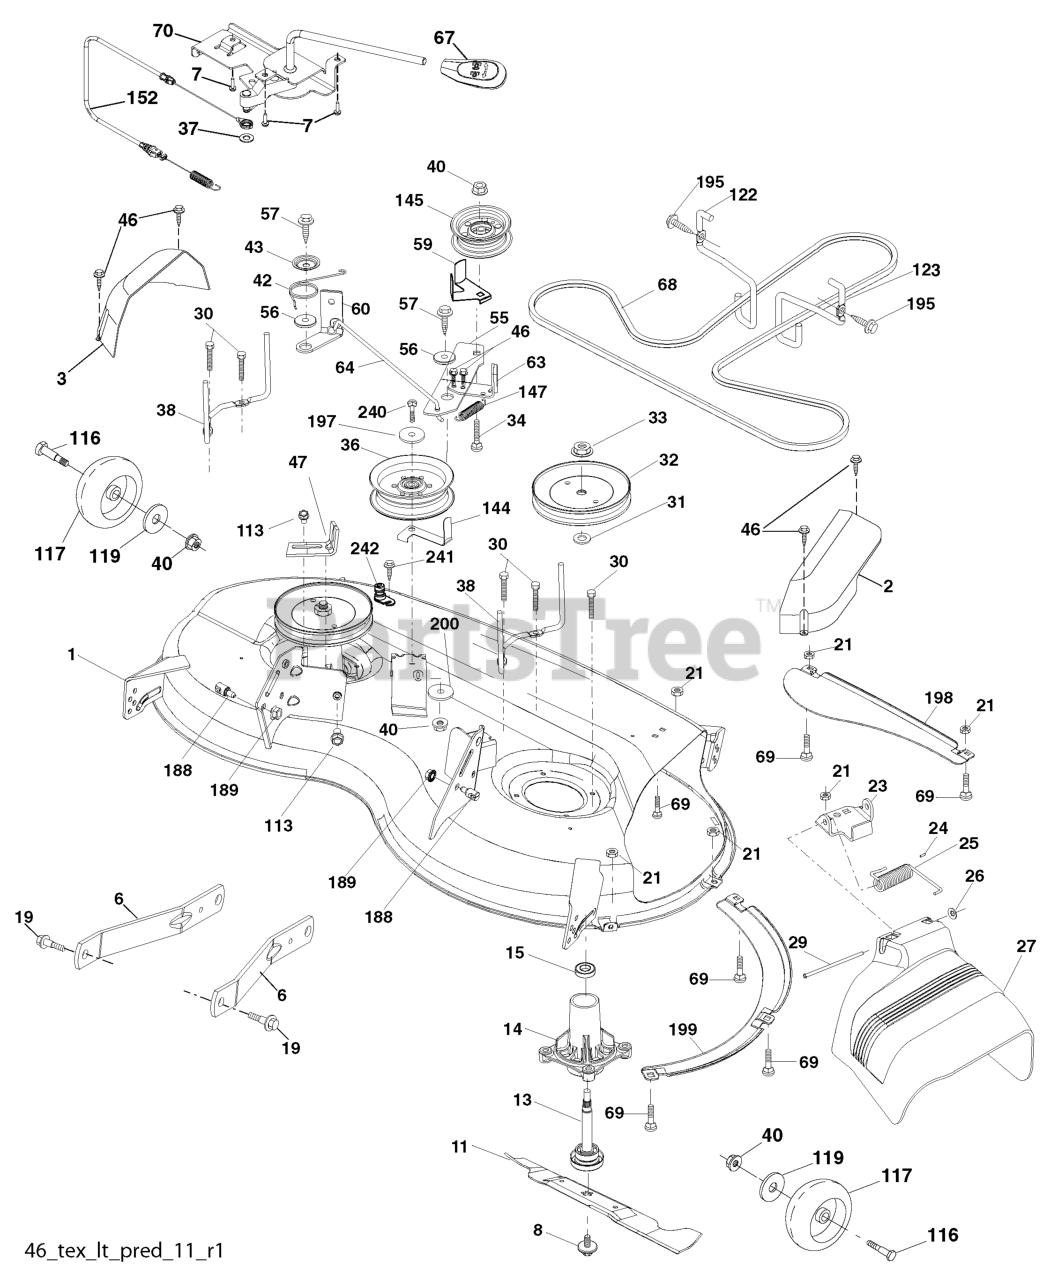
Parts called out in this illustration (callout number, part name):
1	DECK.WELDMENT.46"
2	COVER.MANDREL.RH.46"
3	COVER.MANDREL.LH.46"
6	ARM.SUSPENSION.MOWER.R
7	SCREW.#10 X 0.750.BOS
8	BOLT.WASHER.ASM.7/16-2
11	BLADE.MOWER.46".HI.LIFT
13	SHAFT.ASM.MDRL.N/GREASE.38
14	RP.HOUSING.MANDREL.4PT.
19	BOLT.SHOULDER
21	LOCKNUT
23	BRKT.DEFLECTOR.38"2005+
24	CAP-SLEEVE LT
25	SPRING.TORSION.DEFLECT
26	NUT PUSH M
27	SHIELD.DEFLECTOR.MOWER.46"BLAC
29	ROD.HINGE
30	SCREW, WASHER HEAD
31	WASHER.SPACER.MANDREL
32	PULLEY.MANDREL.5.438.PD
33	NUT.FLANGE.LOCK.TOP
34	BOLT.3/8-16X1.50
36	PULLEY.IDLER.2006
37	WASHER
38	KEEPER.BELT.MANDREL.PULLEY
40	NUT LOCK FLG 3/8-16 UNC
42	SPRING.TORSION.BRAKE
43	SRPING.TORSION.RETAINE
46	SCREW.1/4-20X5/8
47	BRKT.CLUTCH.CABLE
55	IDLER.ARM
56	SPACER.RETAINER
57	SCREW 3/8-16X1
59	GUARD, BELT
60	ARM BRAKE MOWER RH 38"
63	ARM BRAKE MOWER
64	LINKAGE BRAKE
67	HANDLE.CLUTCH.CABLE.LT
68	V-BELT
69	BOLT
70	CLUTCH.ASM.CABLE.HUSQ.TEX
113	BOLT.5/16HEX.WHS.HD
116	BOLT.SHOULDER.3/8-16X3-5/8.
117	RP WHEEL. GUAGE RALLY
119	WASHER
122	KEEPER BELT ENGINE LH
123	KEEPER BELT RH
144	KEEPER.BELT.MOWER
145	PULLEY.IDLER.48"PRIMARY
147	SPRING RETURN
152	CABLE.CLUTCH.CABLE.W/SPRING
188	STUD.FASTNER.W/ANTI-ROTATE
189	NUT LOCK HEX FLANGE 5/16-18
195	SCREW, 3/8-16X3/4
197	WASHER
198	BAFFLE CENTER FRONT
199	BAFFLE FRONT RH
200	WASHER.13/32 X 1 X 1/2.11GUARD
240	BOLT-HEX EAK
241	SCREW.TT.#10-32X.5.3/8.FLANGE
242	PORT.WASHOUT
